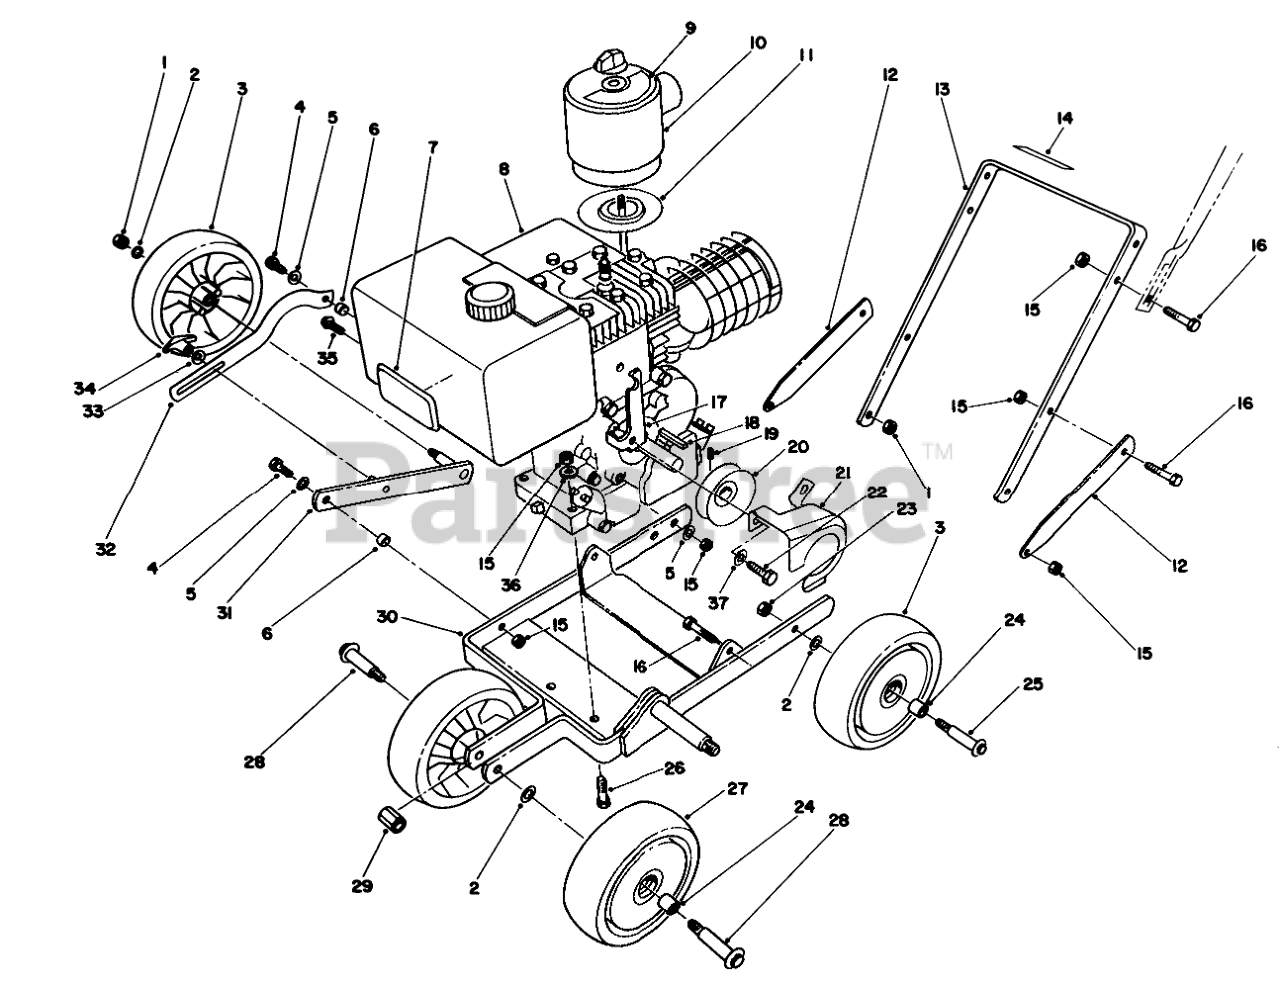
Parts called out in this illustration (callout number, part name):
1	NUT-LOCK
2	WASHER
3	Wheel & Tire Assembly (Incl. Ref. #24)
4	SCREW-HH
5	WASHER-FLAT
6	WHEEL MT BUSHING
7	TORO LOGO PLATE
8	Engine-3 hp.
9	DECAL - WARNING
10	AIR CLEANER COVER WA
11	AIR CLEANER BASE
12	SUPPORT HANDLE
13	LOWER HANDLE
14	DECAL-WARNING
15	NUT-LOCK, NI
16	SCREW-HH
17	SPRING BRACKET
19	SCREW-SET
20	PULLEY (3.5 HP)
21	ENG. PULLEY GUARD
22	SCREW-HH
23	NUT-HEX
24	BUSHING
25	WHEEL BOLT
26	SCREW-HH
27	Wheel & Tire Assembly (Incl. Ref. #24)
28	BOLT-WHEEL
29	HEX SPACER
30	Frame-Edger
31	WHEEL MOUNT WA
32	AXLE LINK
33	BELLEVILLE SPRING WASHE
35	3/8-24 X 1.00HEX BU. HD
36	WASHER-PLAIN
37	WASHER-LOCK
